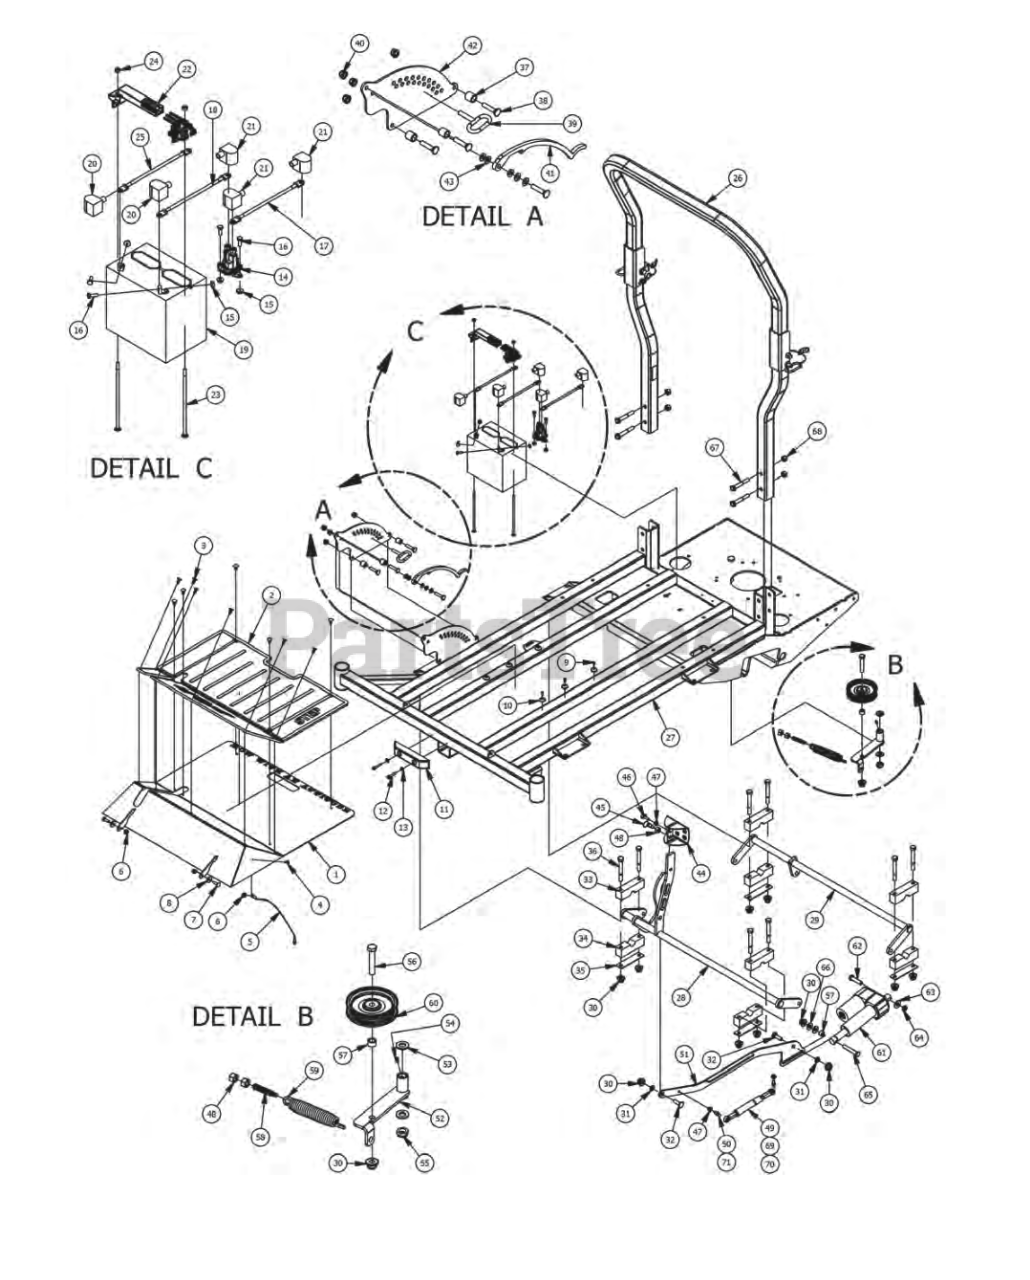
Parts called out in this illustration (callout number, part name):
1	Outlaw Roor Panel
2	Foot Assist Floor Mat
3	Ratchet Fastener
4	1/4x5/8 BS C/S 18-8 SS
5	Floor board Cable W/ Swivel Ends
6	5/16 Flange Nut Zine W/Serrations
7	5/16" x 1" Carriage Bolt
8	360 ID Plastic Washer
9	#101/2" Self Taping Screw
10	Button Bumper
11	8 Rubber Bumper
12	1/4 x 1 1/2" Self Tapping Screw
13	1/4" Flat Washer
15	1/4-20 Hex Flange Nuts Zinc w/Serrations
16	1/4-20x3/4 GR 5 Hex Balts Zinc
17	red battery cable alternator to Started cable
18	12 in red battery cable
20	Black Boot For ground cable
22	Battery Hold Down
23	1/4-20 X Carriage Bolt
24	1/4-20 Hex Nut
25	Starter to chassis cable
26	2015 Outlaw 2x2 Folding ROPS
27	2015 XP Frame
28	2015 Outlaw Act Bar Assembly (Front)
29	2015 Outlaw Act Bar Assembly (Rear)
30	1/2-13 Nylon Flange Nut-Orange
31	Bushing- SF-1620-4
32	1/2 x 1-1/2 Carriage Bolt
33	Two Piece Pillow Block (Male)
34	Two Piece Pillow Block (Female)
35	Two Piece Pillow Block Strap
36	1/2 x4 Bolt (Grade 8)
37	3/4 OD x 1/2 ID x 314 Length
38	3/8 x1 3/4 Carriage Bolt
39	Deck height lever pin
40	3/8 Nylock Flange Nut
41	Outlaw Deck Lever Lock
42	Outlaw Height Indicator Plate (Outer)
43	390 x 750 x .062 Nylon Washer
44	Outlaw Deck Lift Pedal
46	5/16-18 x1 Thumb Screw Zinc
47	5/16 Flanige Nut
48	1/2 Hex Nut
49	200 lb Gas Spring- 54" Deck outlaw
50	10mm Damper Ball Stud-Steering
51	Outlaw Linkage Bar Susp Frame
52	Pump Idler Bracket
53	635 ID Plastic Washer
54	1/4" Press in Grease Fitting
55	5/8 Nylock (1/2 Jam)
56	1/2 x 2 3/4" Hex Bolt
57	1/2 x 1/2 Spacer
58	All Thread-pump Idler Tensioner
59	2009 Deck/Pump Idler Spring
60	43/4" Idler Pulley
62	1/2-13x2 Grade & Hex Bolt
63	1/2" Washer (Grade 8)
64	1/2 Nylcock Nut (1/2 Jam
65	1/2 x 3 Hex Bolt
66	505 Nylon Spacer
67	1/2-13 X 3.25 Hex Bolt-Grade 5
68	1/2 Center Lock Nut
69	250 lb Gas Spring 61" Deck Outlaw
70	300 lb Gas Spring 72" Deck Outlaw
71	13mm Ball Stud (72" Deck Only)
